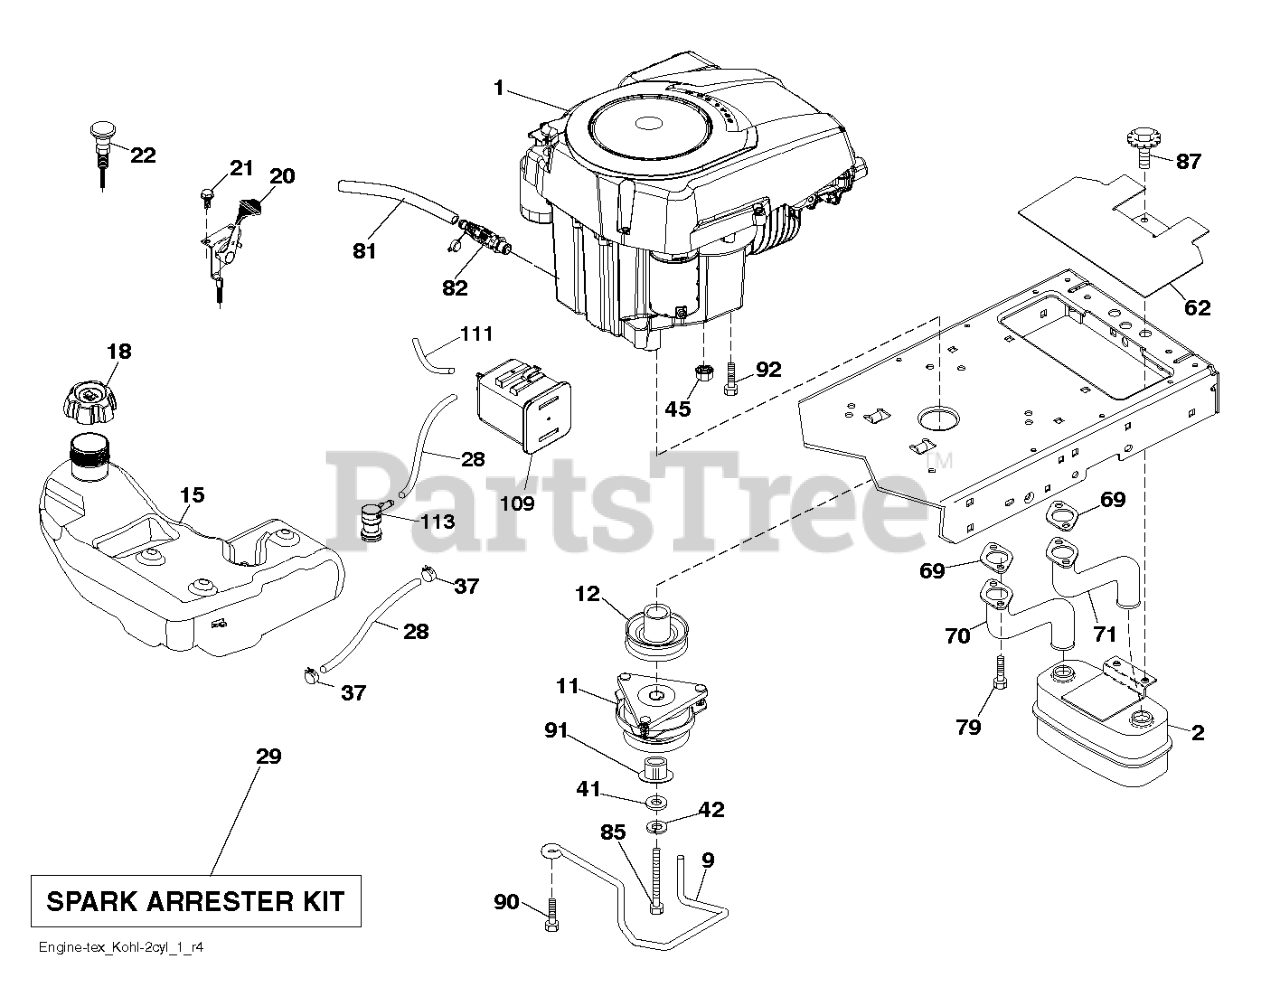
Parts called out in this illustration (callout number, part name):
2	MUFFLER.TWIN.CYL.LOW.TONE
9	KEEPER.BELT.ENGINE.4.2
11	CLUTCH.ELECTRIC.LT.48"*
12	PULLEY.ENGINE.TUFFTORQ
15	TANK.ASM.FUEL.3GA.CARB
18	CAP.ASM.FL.RITCH.3"E10.SYM.498
20	THROTTLE CONTROL
21	SCREW.#10 X 0.750.BOS
22	CONTROL.CHOKE.ERGO.PUSH-IN.BLA
28	LINE.FUEL.64"REAR.EMIS
29	KIT.SPARK ARRESTOR 794945 B&S
37	HOSE CLAMP
42	LOCKWASHER
45	NUT
62	SHIELD.HEAT.MUFFLER
69	GASKET.EXHAUST.KOHL.CV18-CV26
70	RP.PIPE-EXHAUST LH
71	RP.PIPE-EXHAUST RH
79	SCREW.SOCKET HD.5/16-1
81	TUBE, DRAIN OIL ASM.
82	VALUE.OIL.DRAIN
85	BOLT HEX 7/16-20X4-1/4"
87	BOLT.5/16-18UNCX3/4 W/SEMS.BLK
90	SCREW 3/8-16X1
91	BUSHING.1.375OD
92	SCREW 3/8-16X1
109	CANNISTER, CARBON
111	PURGE.LINE.36"REAR.CALIFORNIA
113	VALVE.SLANT.CARTRDG.90 DEG.TEX
